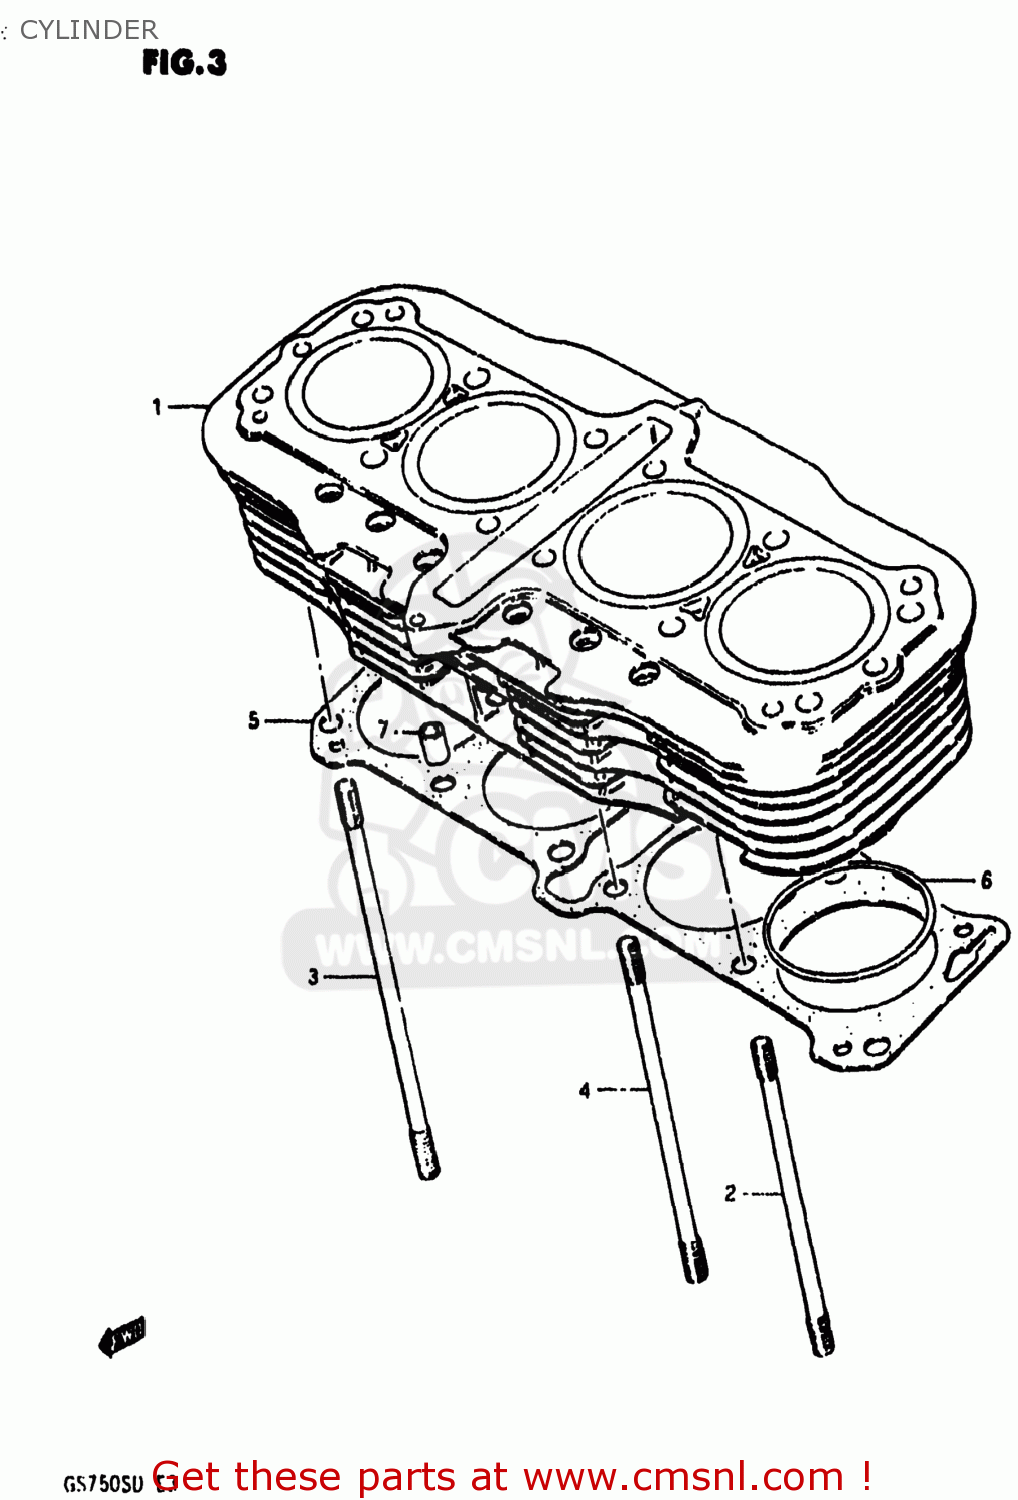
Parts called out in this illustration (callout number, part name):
1	CYLINDER
2	STUD
3	STUD
4	STUD
5	GASKET,CYLINDER (MCA)
6	O RING(D:2,ID:70)
7	PIN
